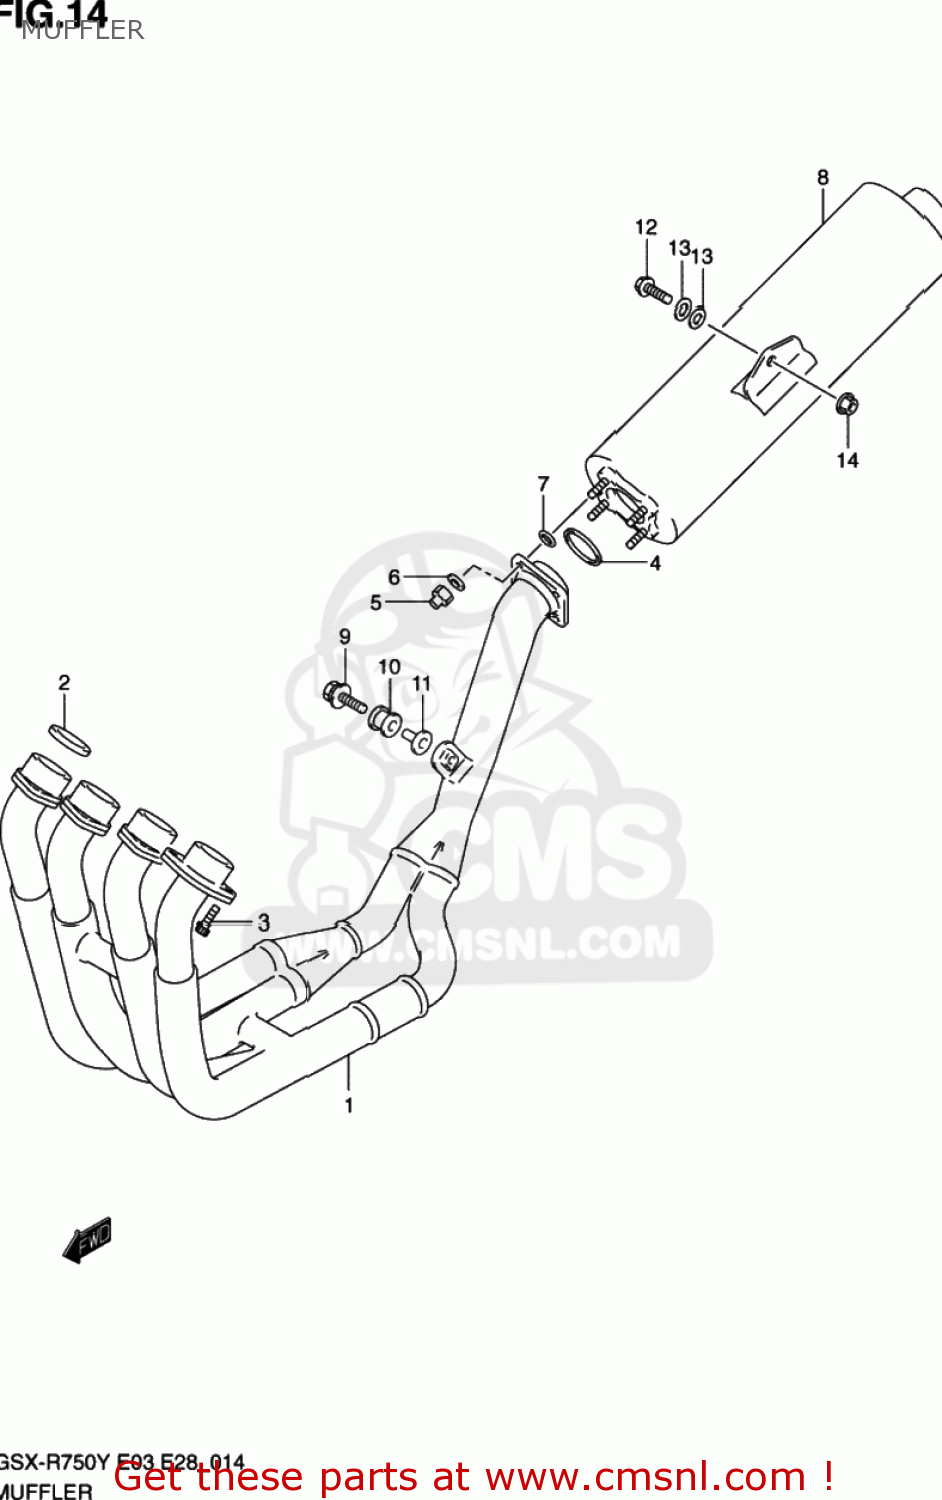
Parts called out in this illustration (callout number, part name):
1	EXHAUST
2	GASKET,EXHAUST PIPE
3	BOLT
4	GASKET,MUFFLER JOINT (NAS)
5	NUT
6	WASHER(8.5X18X1.6)
7	O RING(D:1.9,ID:7.8)
8	BODY,MUFFLER
9	BOLT 8X45
10	CUSHION
11	SPACER(8.6X12X24.2)
12	BOLT(8X35)
13	WASHER(8.5X23X1.5)
14	NUT
